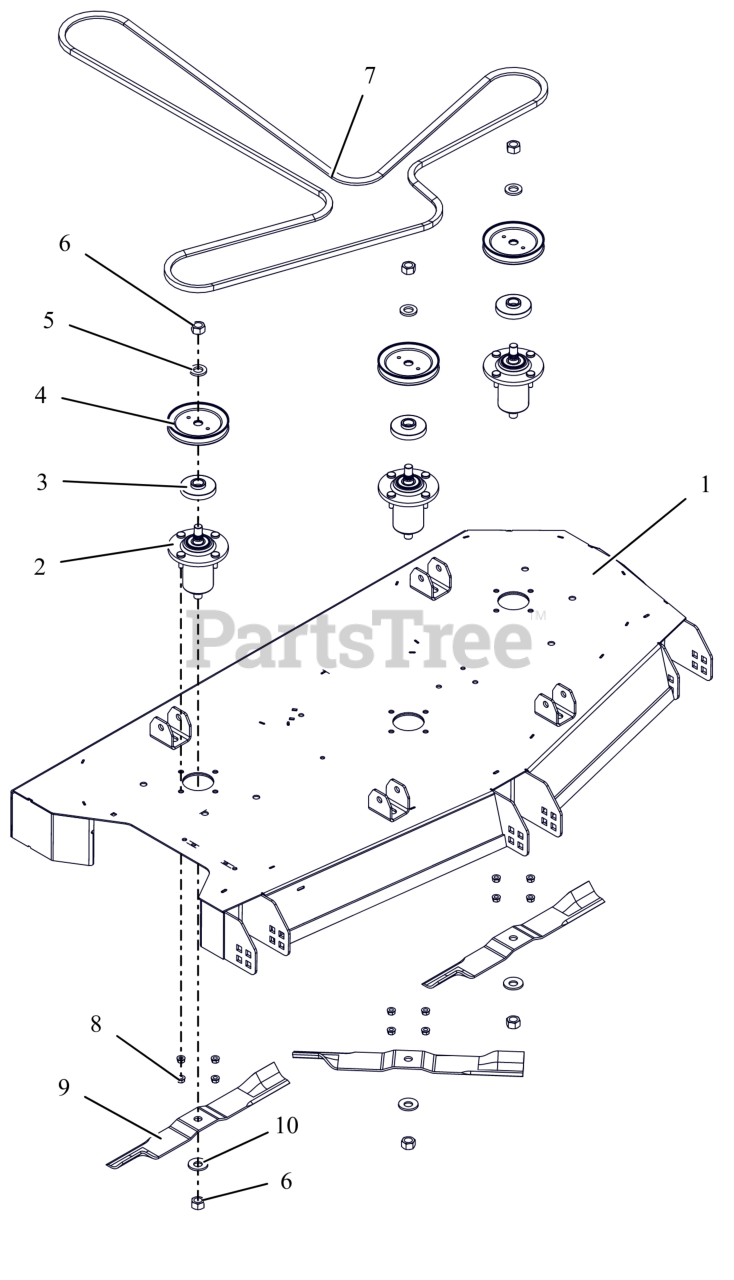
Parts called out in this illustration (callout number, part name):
1	KIT-GRAVELY DECK 52" W/ DECALS
2	ASM, ALUMINUM SPINDLE SUB
3	SHIELD, DUST
4	PULLEY-V-4.75 ODX.625SPLINE ID
5	SPCR- .735 X 1.313 X .165
6	NUT-STD .625-18 ZCC
8	NUT,LK-CTR-FLG .31-18 GF ZCC
9	BLADE- 18.0" MOWER (HI-LIFT)
10	WSHR-BLVL .669X1.535X.138
